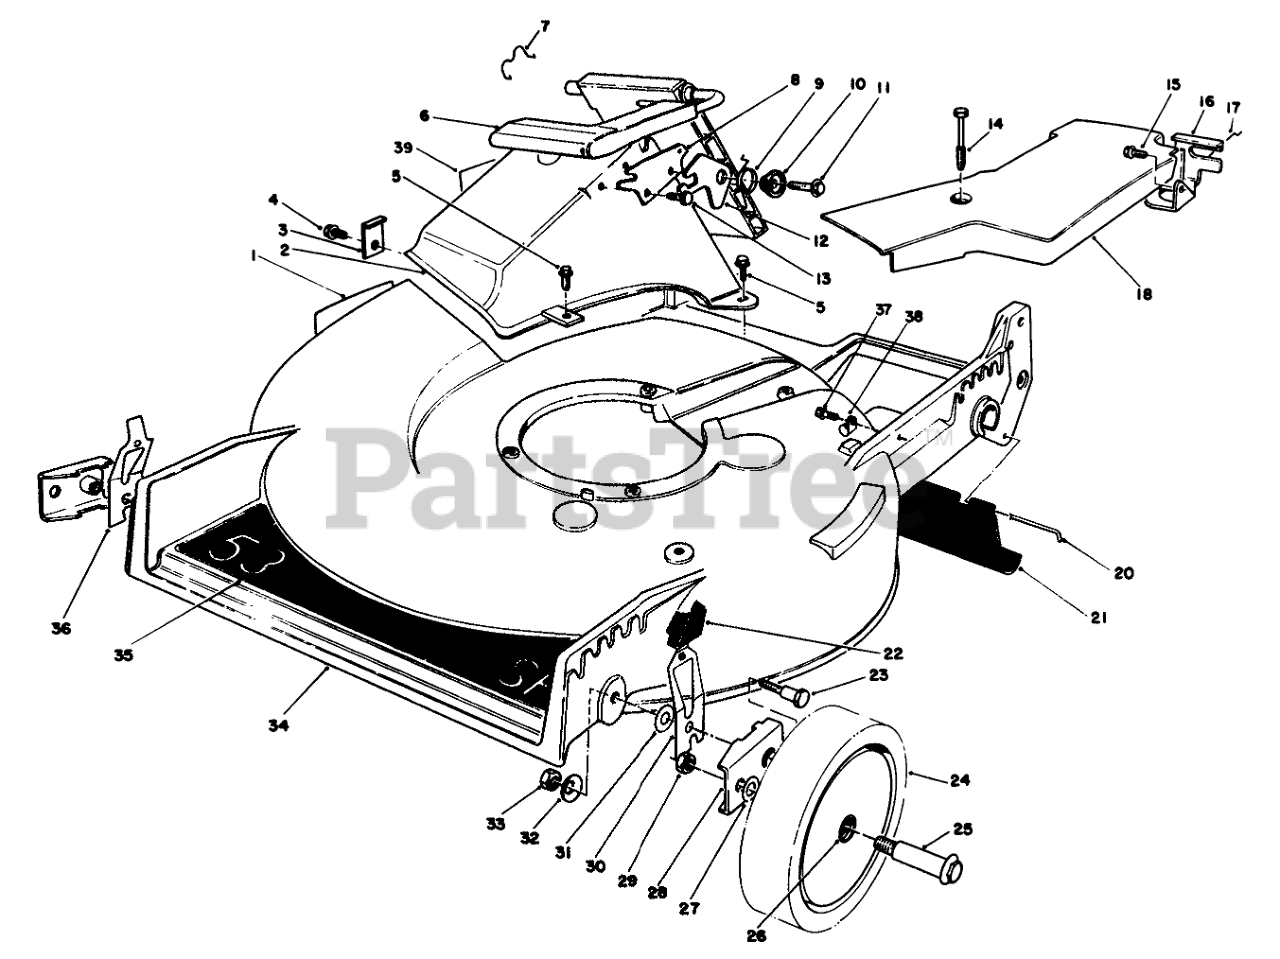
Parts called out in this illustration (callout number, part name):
1	Decal Danger
2	Tunnel-Discharge (Incl. Ref. #39)
3	TUNNEL CLIP
4	SCREW
5	SCREW-HWH
6	Discharge Door Assembly
7	DOOR RET SPRING
8	DOOR LATCH PLATE
9	TORSION SPRING
10	DOOR SPACER
11	SCREW-HWH
12	SAFETY LATCH
13	SCREW-PLASTITE
14	SCREW-HHFTF
15	SCREW-HWHTF
16	Bracket-Traction Adj.
17	RETAINER-CABLE
18	Belt Cover
20	ROD-SHIELD
21	SHIELD-TRAILING
22	KNOB-ARM
23	PIVOT SCREW
24	Wheel & Tire Assembly (Incl. Ref. #26)
25	BOLT-WHEEL
26	BUSHING
27	WASHER
28	HP PIVOT ARM ASM
29	Nut
30	L. HP SPRING ARM ASM
31	WASHER-PIVOT
32	WASHER-BELLEVILLE
33	NUT-LOCK, NI
34	Housing (Incl. Ref. #1)
35	Decal-53
36	R HP SPRING ARM ASM
37	SCREW
38	CLAMP-CABLE
39	DECAL - DANGER
